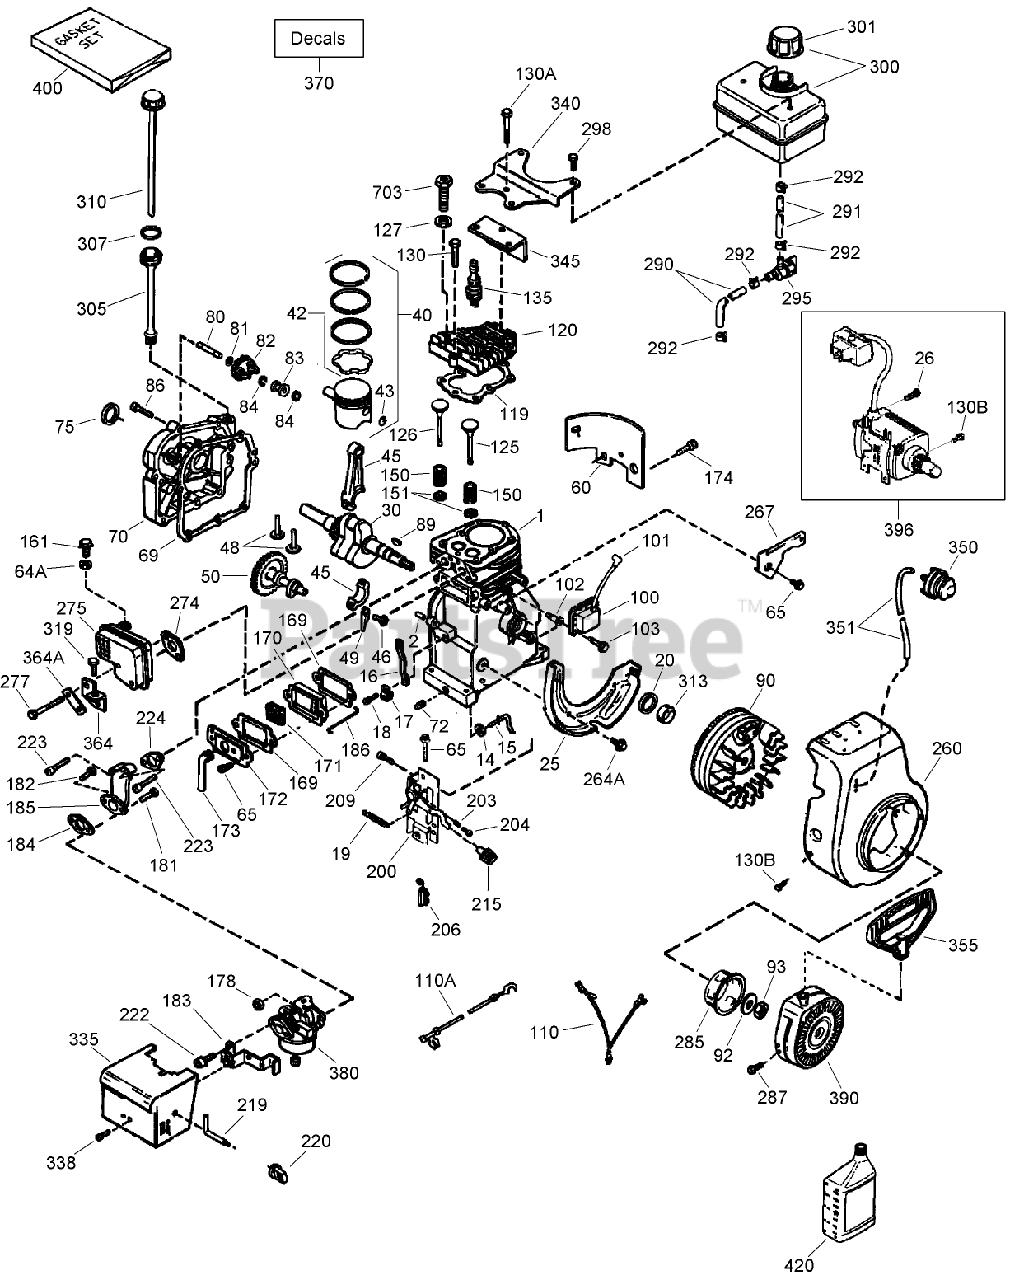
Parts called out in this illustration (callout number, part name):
1	Cylinder Assembly (Incl. Ref. #2, 20, 72
2	Pin-Dowel
14	Washer-Flat
15	Rod-Governor
16	Chute Idler Arm ASM
17	Clamp-Lever, Governor
18	Screw (T-15, 8-32 x 19/64)
19	Spring-Extension
20	Seal-Oil
25	Baffle-Housing, Blower
26	Screw (1/4-20x19/32)
30	Crankshaft ASM
40	Piston, Pin and Ring Set (STD)
40	Piston, Pin and Ring Set (.020 O S)
40	Piston, Pin and Ring Set (.010 O S)
42	51105/51105Z GIL RO
42	Ring Set (STD)
42	FITTING - TANK 3/4"
42	Ring Set (.020 O S)
43	Ring-Retaining, Piston Pin
45	Connecting Rod Assembly (Incl. Ref. #46 49)
46	Bolt-Rod, Connecting
48	Lifter-Valve
49	Dipper-Oil
50	Camshaft
60	Extension-Blower
64A	Washer
65	Screw (10-24 x 9/16)
69	Gasket-Cover, Cylinder
70	Cover-Cylinder (Incl. Ref. #75 80)
72	Plug-Drain, Oil (SQH 1/4-18)
75	Seal-Oil
80	Shaft-Governor
81	Washer-Flat
82	Governor Gear ASM
83	Spool-Governor
84	Ring-Retaining
86	Screw (1/4-20 x 1-1/4)
89	Key-Flywheel
90	Flywheel
92	Washer-Belleville
93	Nut-Flywheel
100	Ignition-State, Solid
101	Cover-Spark Plug
102	Stud-Mounting, Solid State
103	Screw (T-15, 10-24 x 15/16)
110	Wire-Ground
110A	Wire-Ground (Green, 5.5)
119	Gasket-Head, Cylinder
120	Head-Cylinder (Includes 130A)
125	Exhaust Valve (Std.)(Incl. 151)
125	Valve-Exhaust (1/32 O S)
126	Valve-Intake Standard (Incl. Ref. #151)
126	Valve-Intake 1/32" oversize (Incl. Ref. #151)
127	Washer-Flat
130	Screw (5/16-18x1-1/2)
130A	Screw (5/16-18 X 2)
130B	Screw (1/4-20 x 1/2)
135	Spark Plug-Resistor (R J19 L M)
150	Spring-Valve
151	Cap-Valve, Spring
161	Screw
169	Gasket-Cover, Valve
